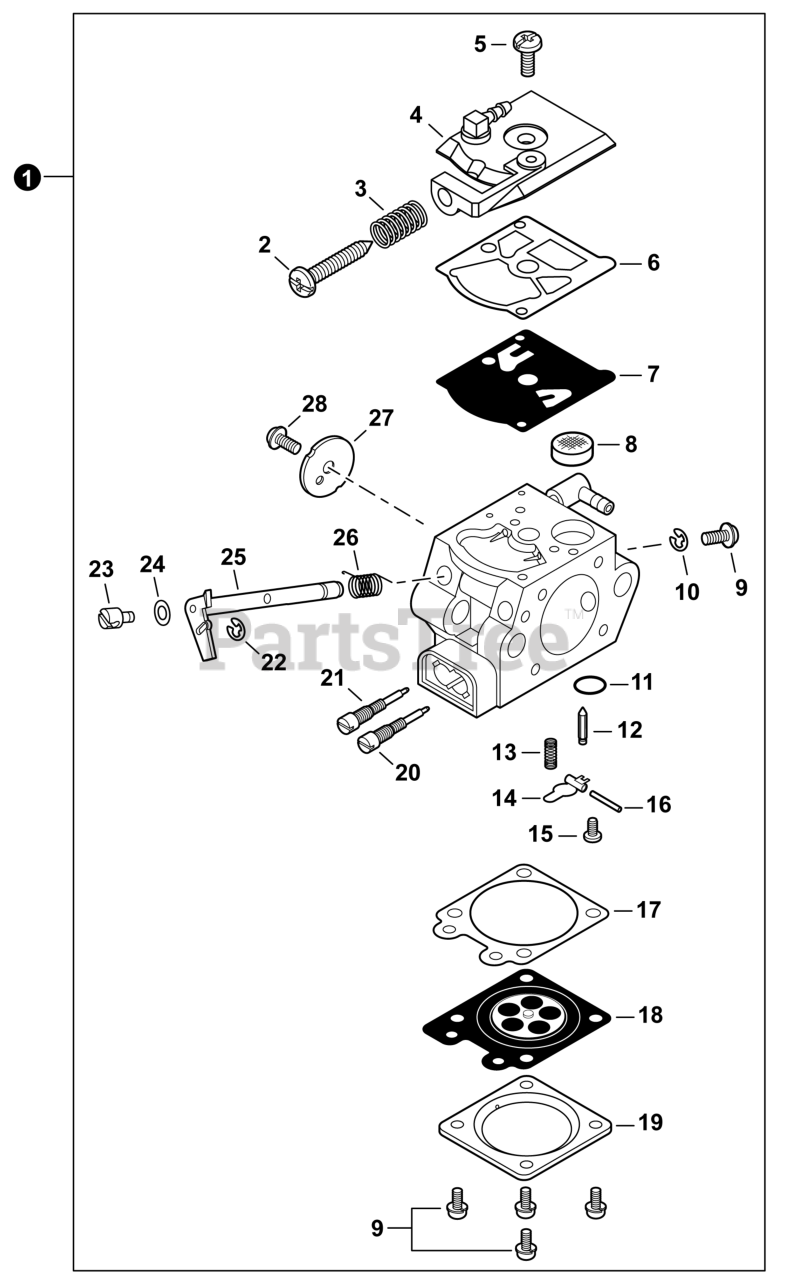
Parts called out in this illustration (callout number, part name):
1	CARBURETOR WT-1046
2	SCREW, IDLE ADJUST
3	SPRING, IDLE ADJUST
4	COVER, FUEL PUMP
6	GASKET, FUEL PUMP
7	DIAPHRAGM, FUEL PUMP
8	SCREEN, FUEL INLET
10	CLIP, THROTTLE SHAFT
11	PLUG, WELCH
12	VALVE, INLET NEEDLE
13	SPRING, METERING LEVER
14	LEVER, METERING
15	SCREW, METERING LEVER PIN
16	PIN, METERING LEVER
17	GASKET, METERING DIAPHRAGM
18	DIAPHRAGM, METERING
19	COVER, METERING DIAPHRAGM
20	NEEDLE, MIXTURE
21	NEEDLE, MIXTURE
22	RING, RETAINING
25	SHAFT, THROTTLE
26	SPRING, THROTTLE
27	VALVE, THROTTLE
